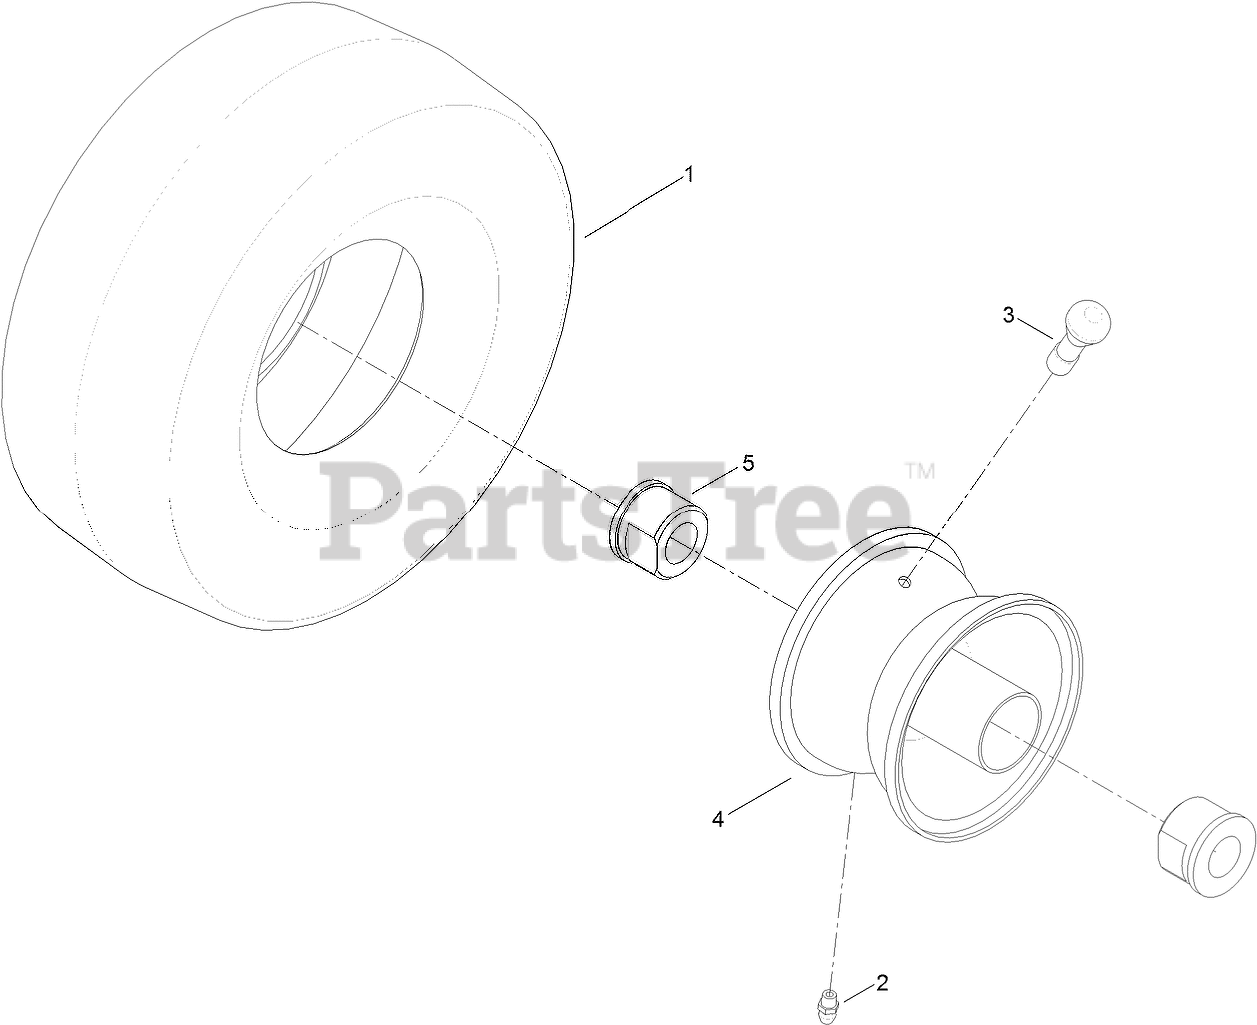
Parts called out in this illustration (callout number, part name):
1	TIRE-SMOOTH (Cst)
2	FITTING-GREASE
3	STEM-VALVE
5	BUSHING-FLANGE
